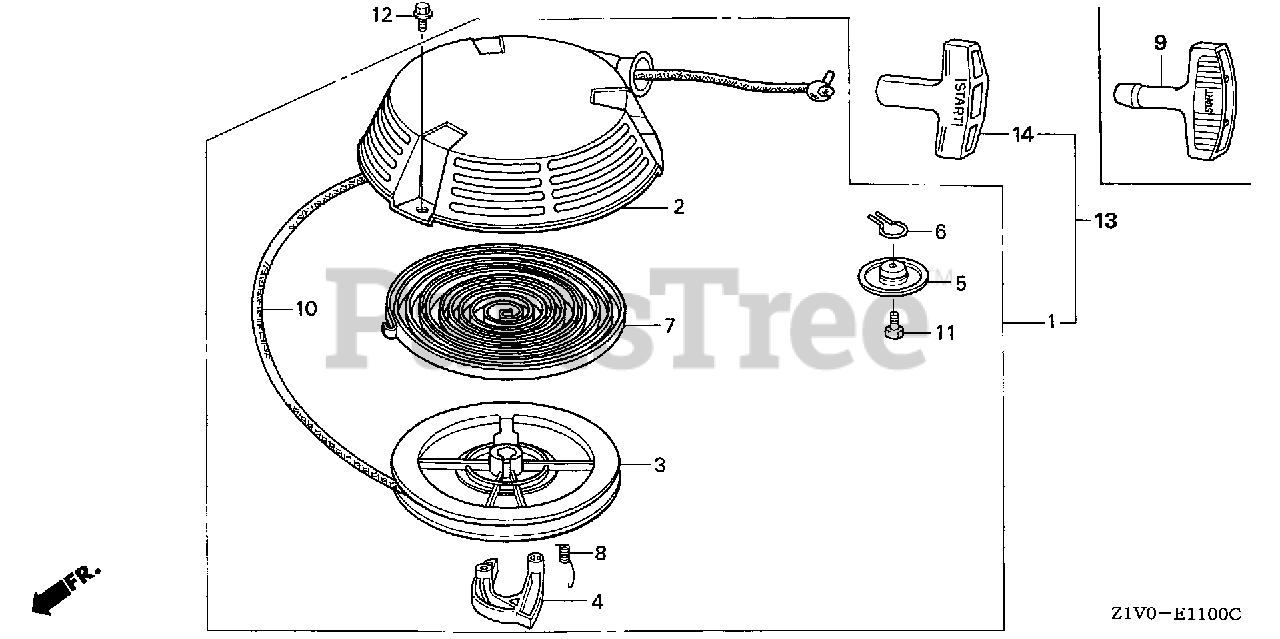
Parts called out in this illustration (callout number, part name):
2	CASE, RECOIL STARTER *NH1* (BLACK) (NOT AVAILABLE)
3	PULLEY, RECOIL STARTER
4	RATCHET, STARTER
5	PLATE, FRICTION
6	SPRING, FRICTION
7	SPRING, RECOIL STARTER
8	SPRING, RETURN
10	ROPE, RECOIL STARTER
10	ROPE, LONG (55")
11	BOLT, HEX. (6X12)
12	BOLT, FLANGE (6X8)
13	STARTER ASSY., RECOIL *NH1* (BLACK) (NOT AVAILABLE)
14	KNOB, RECOIL STARTER
